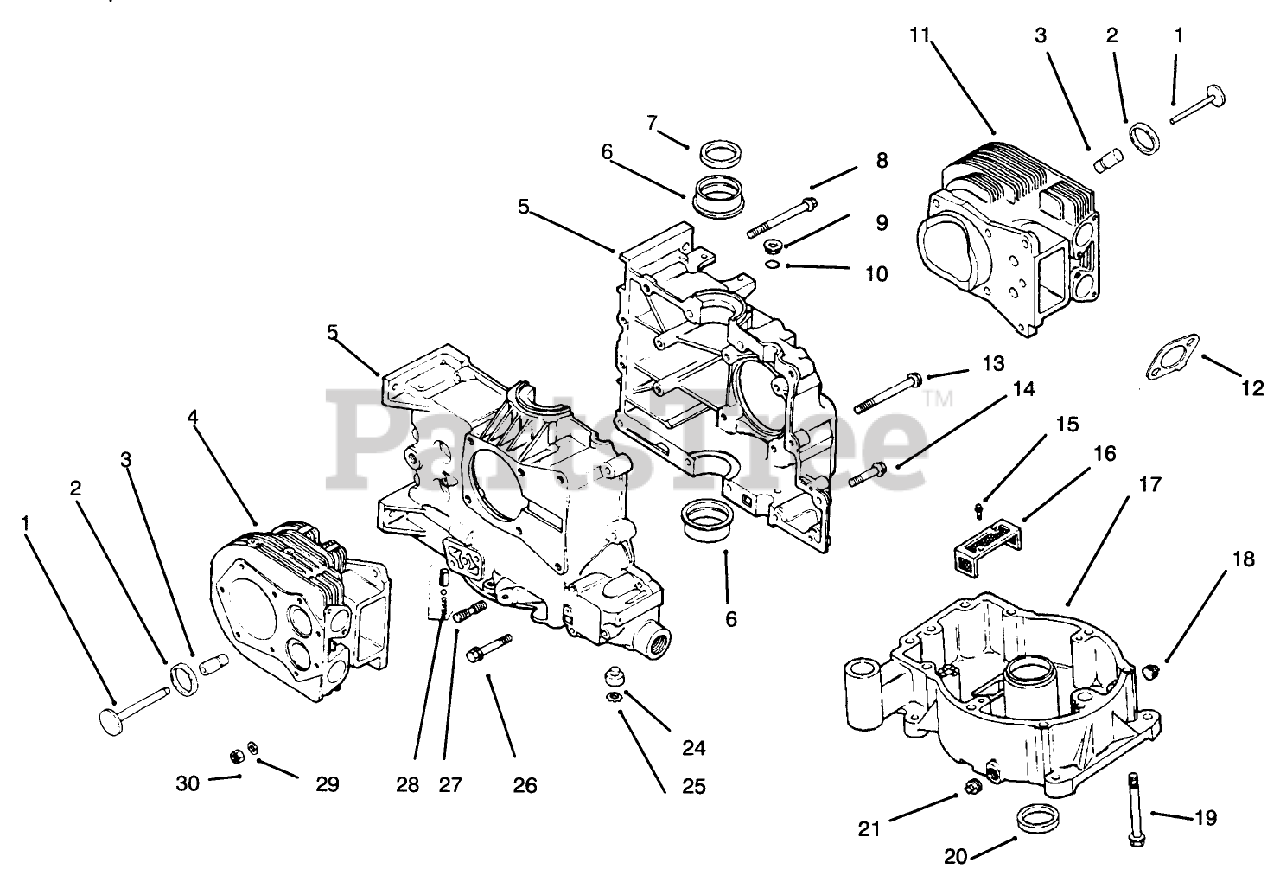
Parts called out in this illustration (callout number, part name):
1	Valve Exhaust (Ref)
2	Inset-Valve Seat
3	Guide-Valve
4	Kit-#2 Cylinder Barrel (Incl. Ref. #1-3)
5	Crankcase (Ref. Short Block)
6	Bearing-Sleeve (Std.)
7	SeaI-RearOil
8	Screw-Hex Flange
9	Plug
10	O-Ring
11	Kit-#2 Cylinder Barrel (Incl. Ref. #1-3)
12	Gasket-Exhaust
13	Screw-Hex. Flange
14	Screw-Hex. Flange
15	Screw
16	Filter-Oil Pickup
17	Pan-Oil
18	Plug-Hex Countersunk
19	Screw-Hex. Washer Hd.
20	SeaI-RearOil
21	Plug
24	Shaft-Governor
25	Ring-Retaining
26	Screw-Hex. Flange
27	Stud-Step
28	Kit-Oil Relief
29	Washer-Flat
30	Nut
